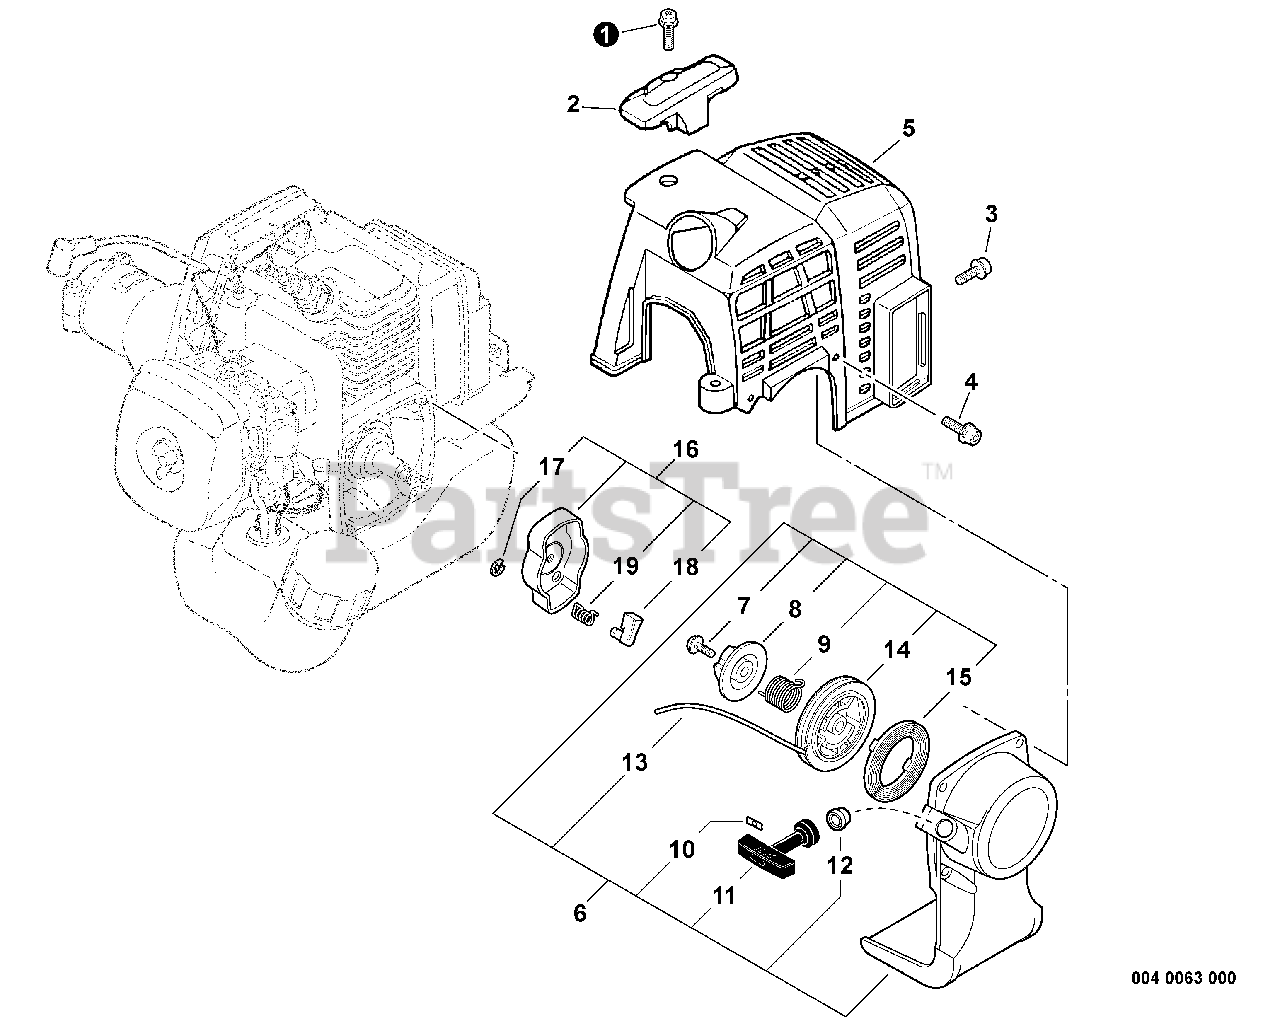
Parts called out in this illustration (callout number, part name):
1	SCREW - 5X16
2	GUARD - TOP
3	SCREW - 4X8
4	SCREW - 4X16
5	COVER, ENGINE
6	STARTER ASSY
7	SCREW
8	PLATE, CAM
9	SPRING, DAMPER
10	RETAINER, ROPE
11	GRIP, STARTER
12	GUIDE, ROPE
13	ROPE, STARTER - 3X700
14	REEL, ROPE
15	SPRING, REWIND
16	STARTER PAWL ASSY
17	RING, RETAINING - 4
18	PAWL, STARTER
19	SPRING, RETURN
